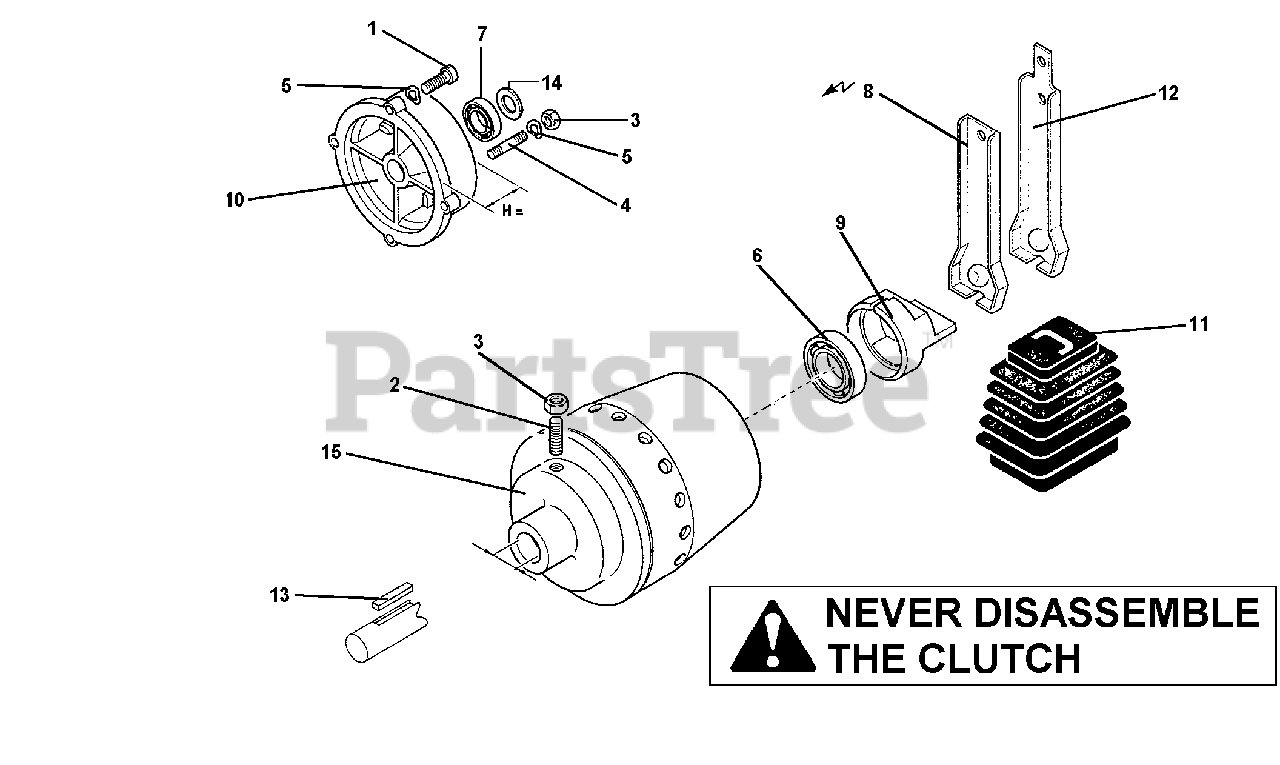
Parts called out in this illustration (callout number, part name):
1	SCREW 5/16X7/8
2	SCREW M8X30
4	STUD,M8X40X14X14
5	WASHER, WAVE
6	BEARING,M17X40X12
7	BEARING,20X47X14
8	CLUTCH LEVER, ELECTRIC START
9	CONE PUSHER
10	FLANGE, 5HP B&S ENGINE
12	LEVER, RECOIL START
14	WASHER, 5HP B&S
15	CLUTCH, 5HP B&S
